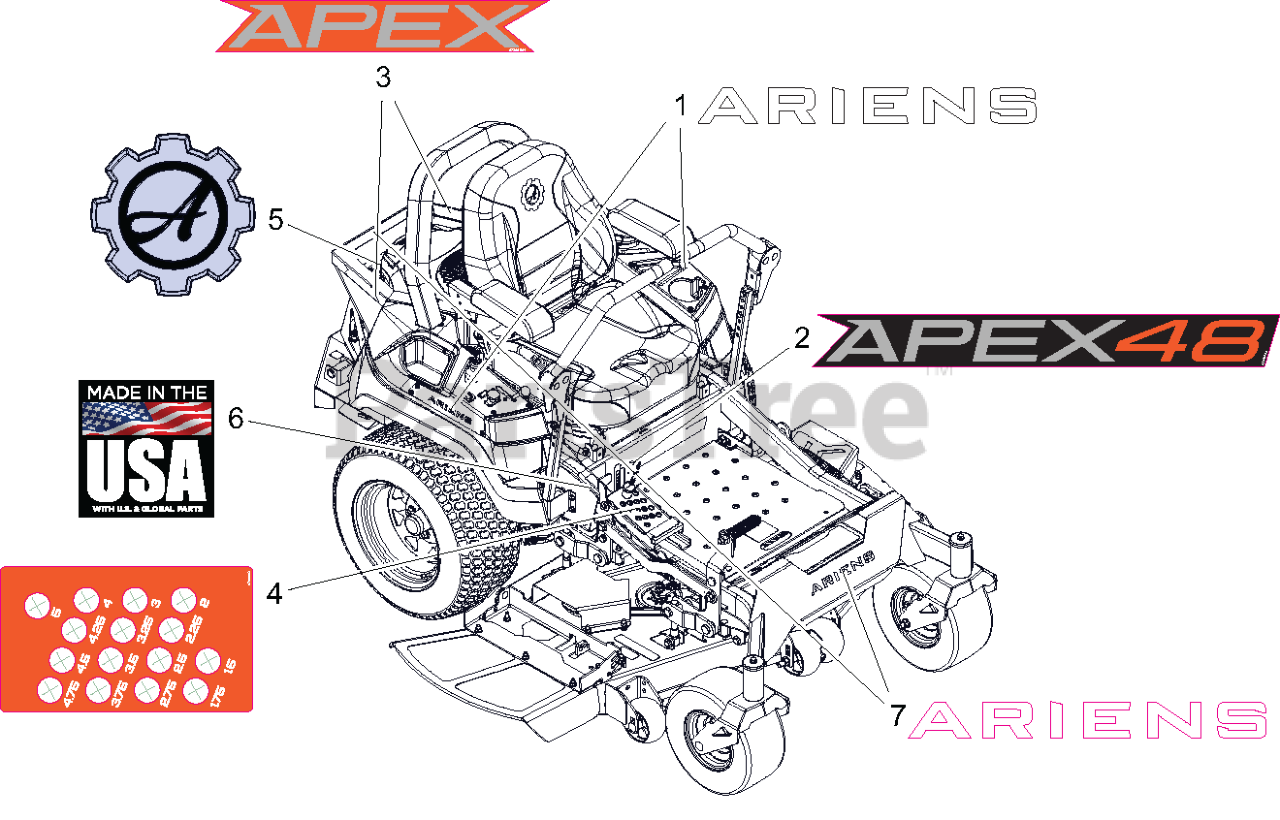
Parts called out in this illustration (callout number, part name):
1	DECAL, ARIENS (6.50")
2	DECAL, 48" APEX KICKPLATE
3	DECAL, APEX FENDER
4	DECAL, ARIENS HOC
5	DECAL- ARIENS GEAR BADGE
6	DECAL, MADE IN USA
7	DECAL - ARIENS 9.625"
